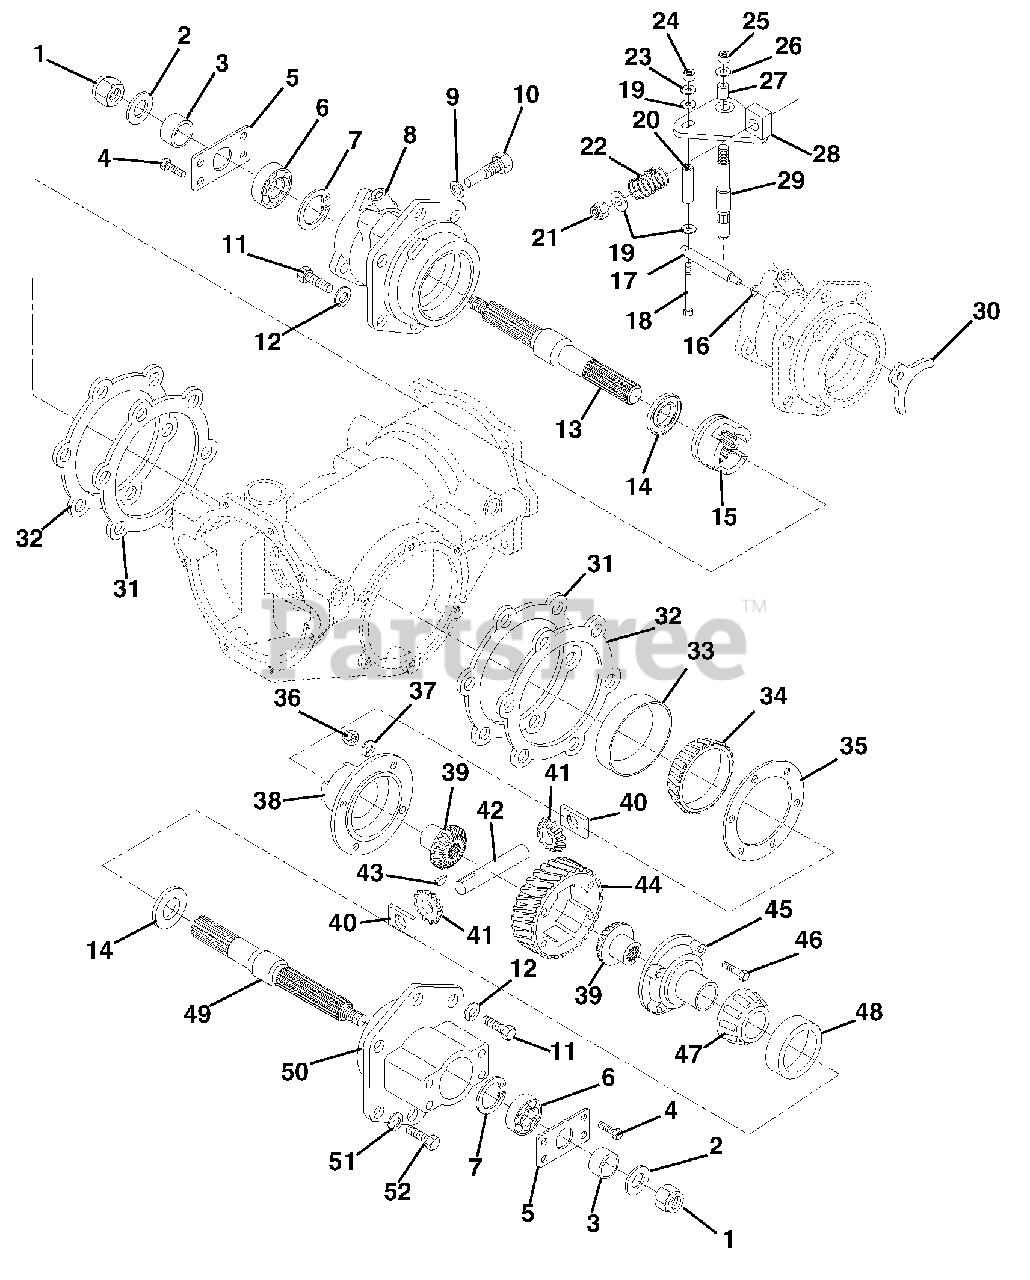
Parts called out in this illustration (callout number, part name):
1	Nut-Locking-Jam-Nylon .75-10
2	Washer-Flat .812 x 1.469 x .134
3	Bushing-Sleeve 1.02 x 1.37 x 1.37
4	Bolt-Hex .38-16 x .75 Grade 5
5	Plate-End
6	Bearing-Ball 1.0 x 2.0 x .56
7	Ring-Retaining-Internal 2.210 x .062
8	Housing-Axle-2 Speed
9	Washer-Nut .63 x .875 x .062
10	Bolt-Hex .62-18 x .493 x 1.25
11	Bolt-Hex .50-13 x 1 Grade 5
12	Washer-Locking .50
13	Axle-Straight Differential Locking
14	Seal 1.188 x 2.000 x .250
15	Clutch-Sliding Differential Locking
16	O-Ring .437 x .625 x .093
17	Pin-Clutch Sliding
18	Bolt-Round Head Square Neck .25-20 x 2.25
19	Washer-Flat-Steel .406 x .812 x .065
20	Bushing-Sleeve .277 x .375 x 1.37
21	Nut-Locking-Nylon .375-16
22	Spring-Compression .067 x .72 x 2.0
23	Washer-Flat-Steel .281 x .62 x .065
24	Nut-Locking-Nylon .250-20
25	Nut-Locking-Nylon .312-18
26	Washer-Flat-Steel .344 x .688 x .065
27	Bushing-Sleeve .377 x .503 x .88
28	Weldment-Arm Shifter
29	Pivot-Stationary
30	Yoke-Shifting
31	Gasket-Axle Housing
32	Shim-Axle Housing
33	Bearing-Race 4.34 x .741
34	Bearing-Cone 2.69 x .87
35	Shim .005 Clutch Worm Gear
36	Nut-Hex .312-24
37	Washer-Locking-Internal .313 x .030
38	Housing-Differential Locking
39	Gear-Differential Bevel
40	Block-Drive
41	Gear-Spider Bevel
42	Pin-Spider Pinion
43	Key-Woodruff .13 x .38
44	Gear-4 Lead Worm
45	Housing-Differential
46	Bolt-Hex .31-24 x 2.75
47	Cone-Roller Bearing 50mm x 21.5mm
48	Cup-Roller Bearing 82mm x 17mm
49	Axle Straight
50	Housing Axle
51	Seal-Oil Drain .563 x 1.250 x .091
52	Bolt-Hex .50-13 x 1.312 Grade 5
